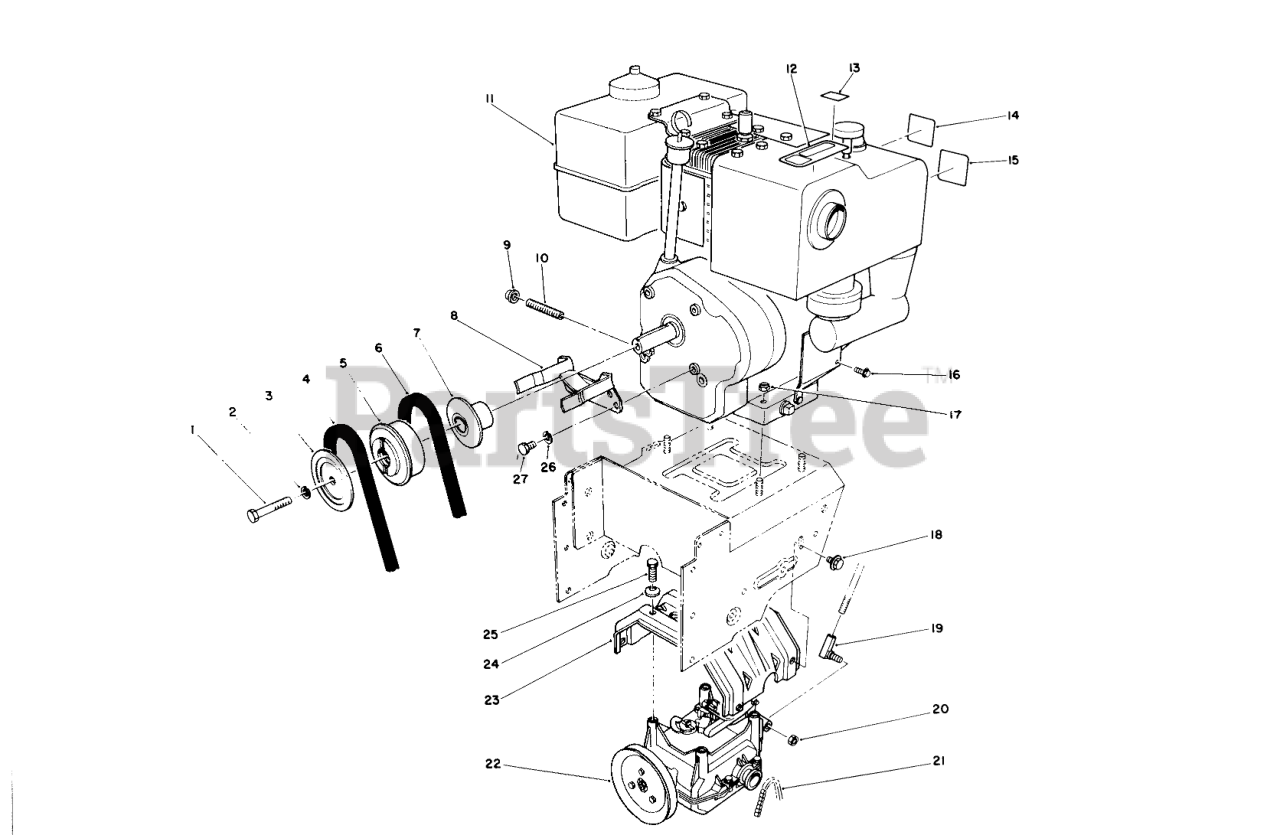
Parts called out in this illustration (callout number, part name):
1	SCREW-HH
2	WASHER-LOCK
3	SHEAVE-HALF, IMPELLER
4	V-BELT, IMPELLER
5	PULLEY-ENGINE, CENTER
6	V-BELT, TRACTION
7	SHEAVE-HALF, TRACTION
8	Guide-Belt
9	CAP-PIPE
10	NIPPLE-PIPE
11	Engine-Briggs & Stratton Model No. 252416 Type No . 0756-01 (Model No. 38580 Only)
12	Decal-Hot
13	DECAL - THROTTLE, INT'L
14	DECAL - PRIMER, INT'L
15	DECAL - CHOKE
16	SCREW-HH
17	NUT-HF
18	SCREW-HHF
19	JOINT-BALL
20	NUT-LOCK, NI
21	CHAIN
22	TRACTION GEARCASE ASM
23	Frame-Transmission
24	WASHER-SPRING
25	SCREW-HWHTF
26	WASHER-LOCK
27	SCREW-HH
